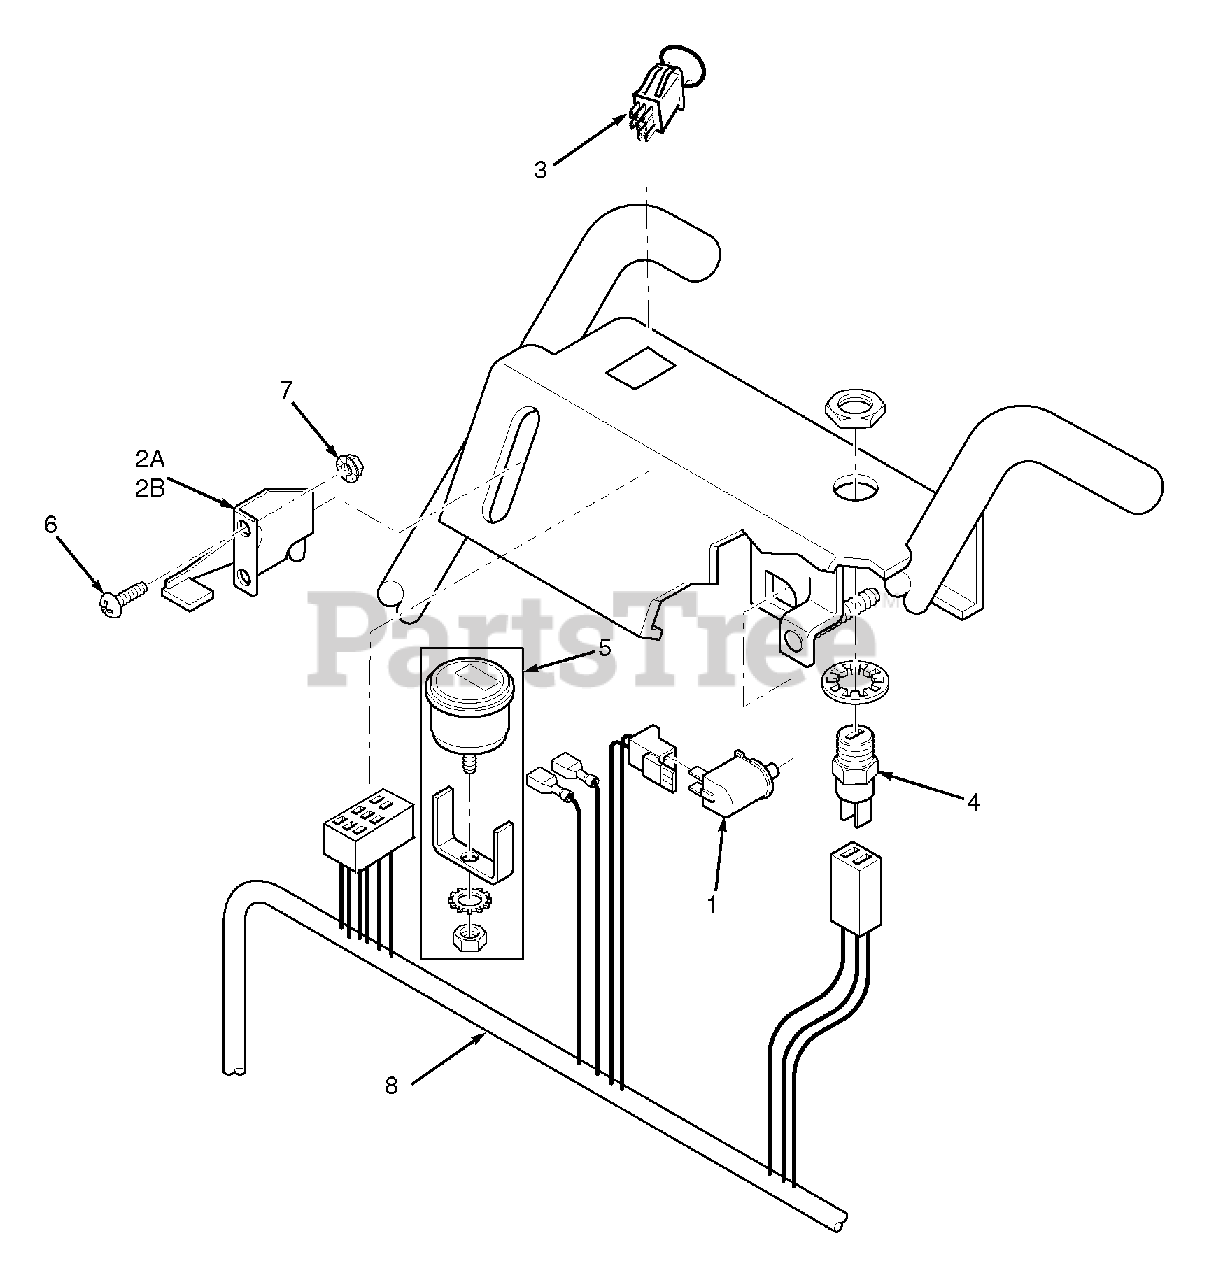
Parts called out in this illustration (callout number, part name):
1	Switch, Neutral Interlock
2A	Throttle Control
2B	Throttle Control
3	Engagement Switch, Electric Clutch
4	Key Switch
5	Hour Meter (dealer installed)
6	Screw, #10-32 x .50 Phillips Washer Head
7	Nut, #10-32 Serrated Flange Hex Head
8	Handle Wire Harness, Manual Start
NS	Clamp, Wire Harness
